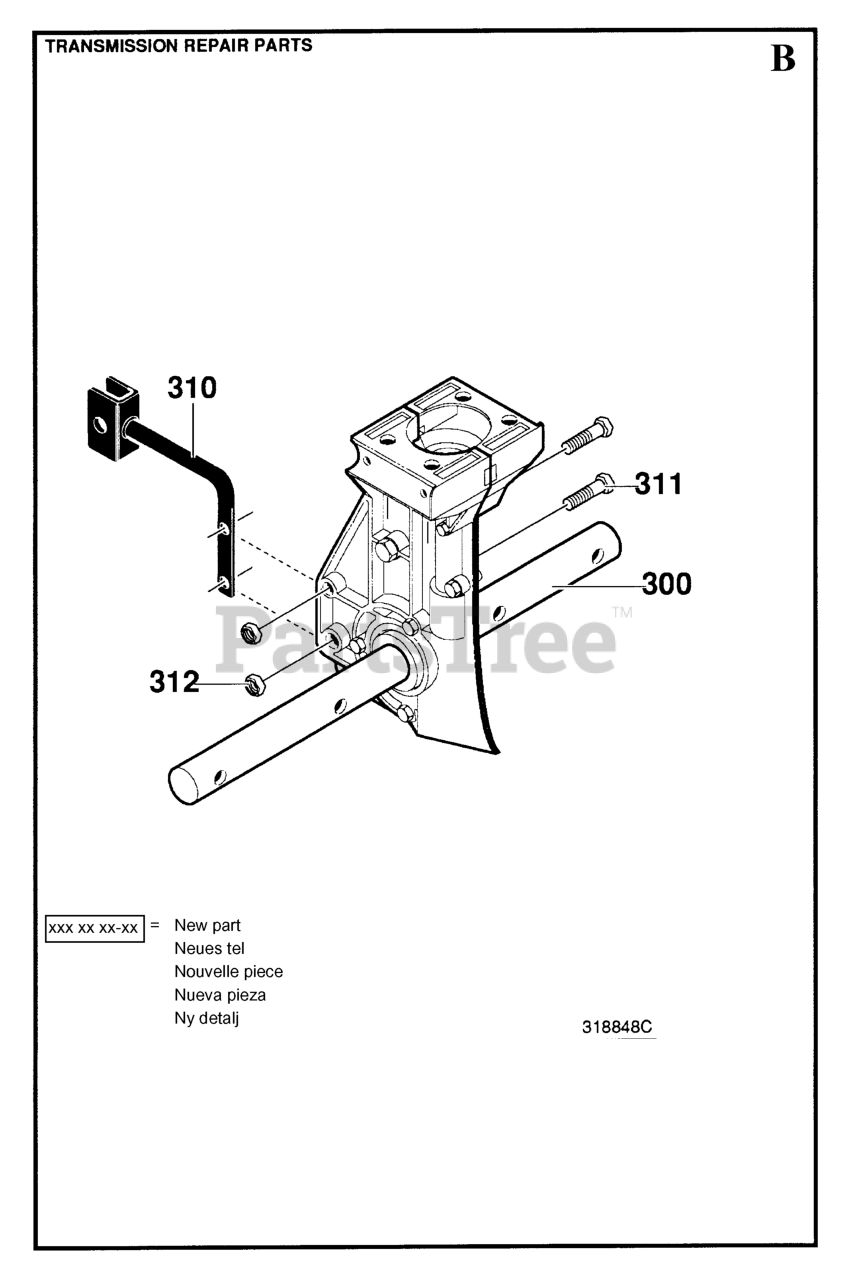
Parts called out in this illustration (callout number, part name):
300	TRANSMISSION
311	Bolt, Hex Fin. 1/4-20 UNC x 1-1/2
312	NUT.CROWNLOCK.1/4
